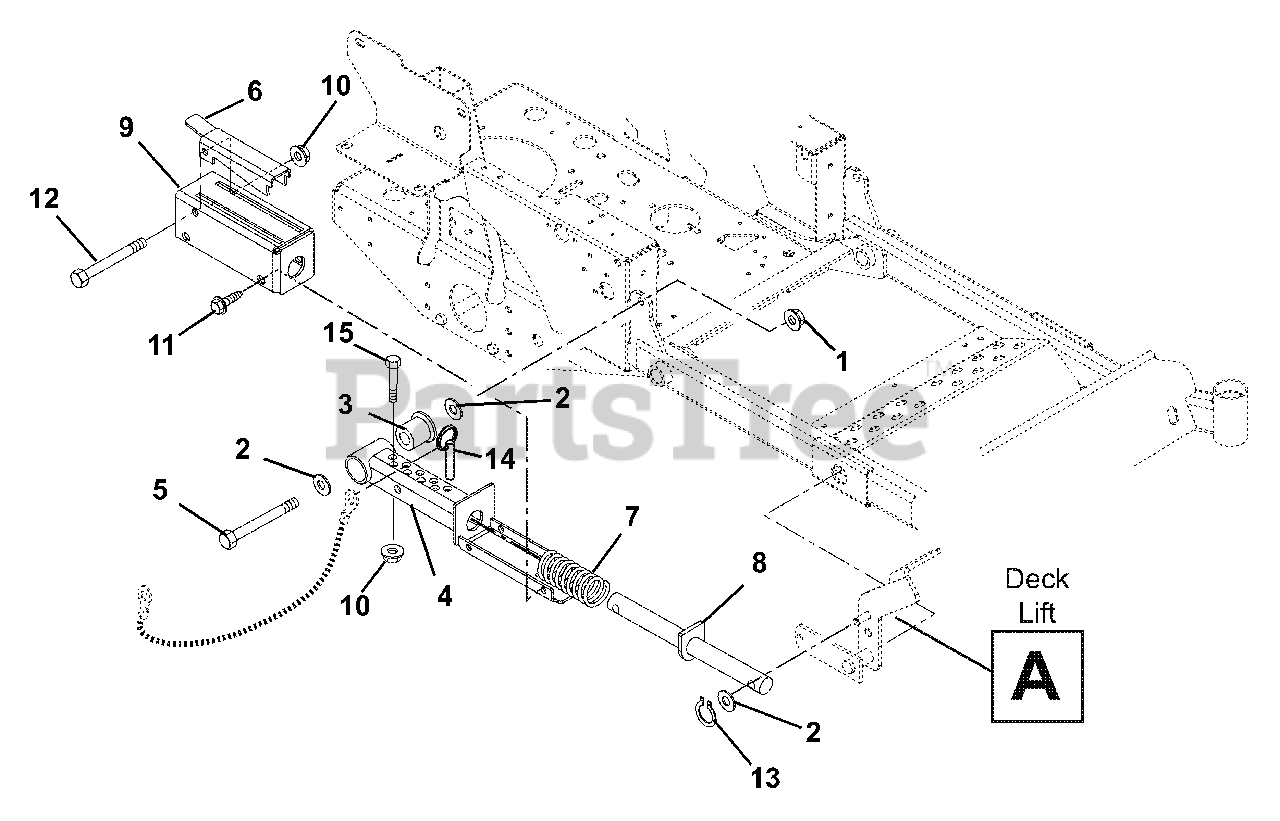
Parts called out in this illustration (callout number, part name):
1	@NUT-LK-NYL-FLG .50-13 YWZC
2	WSHR-FL-STL .531X1.250X.10 YWZ
3	BEARING, PEDESTAL
4	WMT, MECHANICAL LIFT
5	@BLT-HEX .50-13X3.75 GR5 YWZC
6	LOCK-UP, MECH LIFT
7	SPR-COMP 1.13X1.48X5.10 WD 165
8	WMT, MECH LIFT SHAFT (.50)
9	WMT, MECH LIFT COVER
10	@NUT-LK-NYL-FLG .38-16 YWZC
11	@SCR-TAP .38-16X.50 HWH TR YWZ
12	@BLT-HEX .38-16X3.25 GR5 YWZC
13	RG-RTNG-EXT .500X.050 (SNAP)
14	PIN, SPRING BALL .375OD X 1.50
15	@BLT-HEX .38-16X2.00 GR5 YWZC
